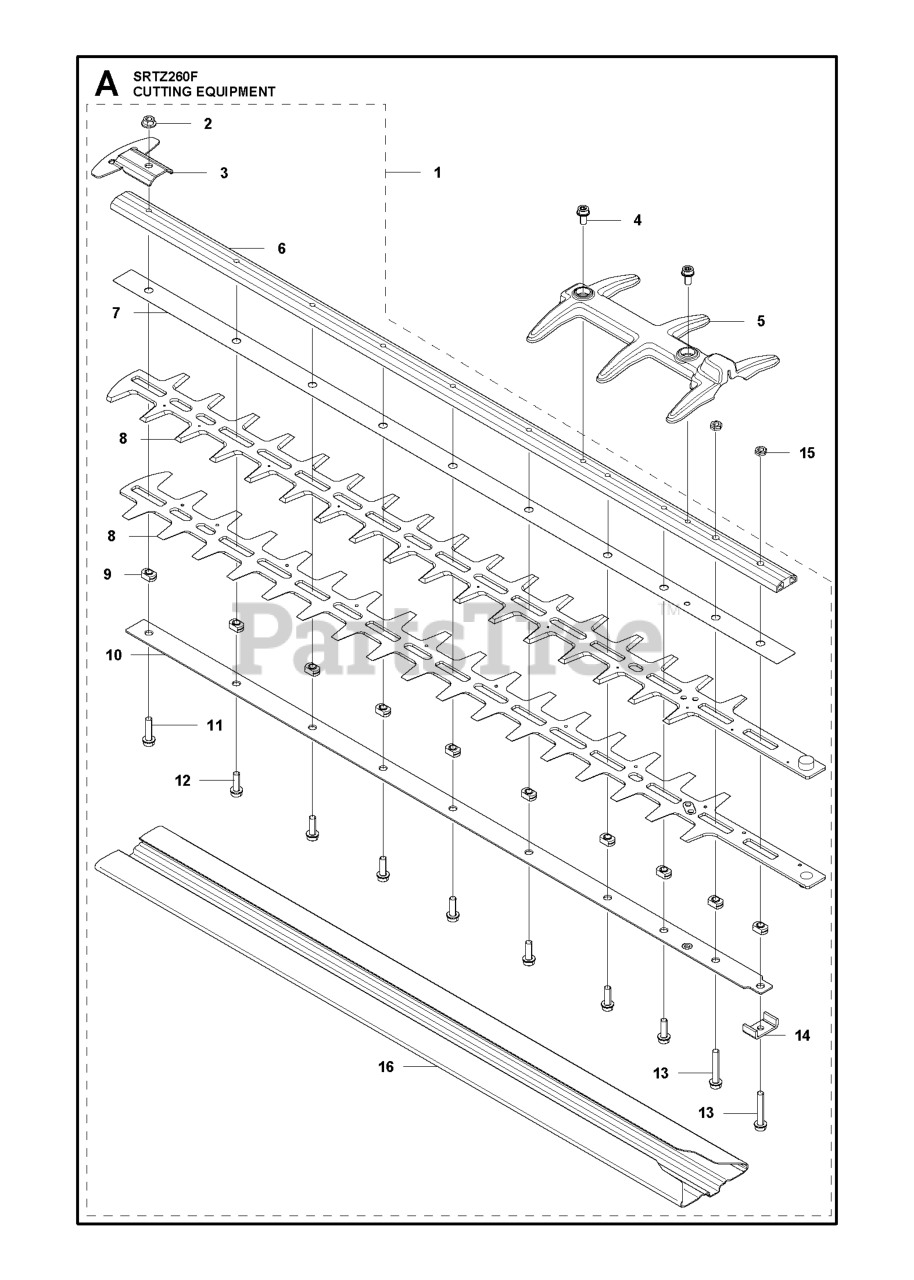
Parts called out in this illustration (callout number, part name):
1	CUTTING DECK
3	PROTECTION BLADE TIP
4	SCREW ITXSCM
6	BAR CUTTING DECK
7	WEAR PLATE CUTTING DECK
8	BLADE ASSY
9	SPACER CUTTING DECK
10	BAR LOWER
14	BRACKET CUTTING DECK
